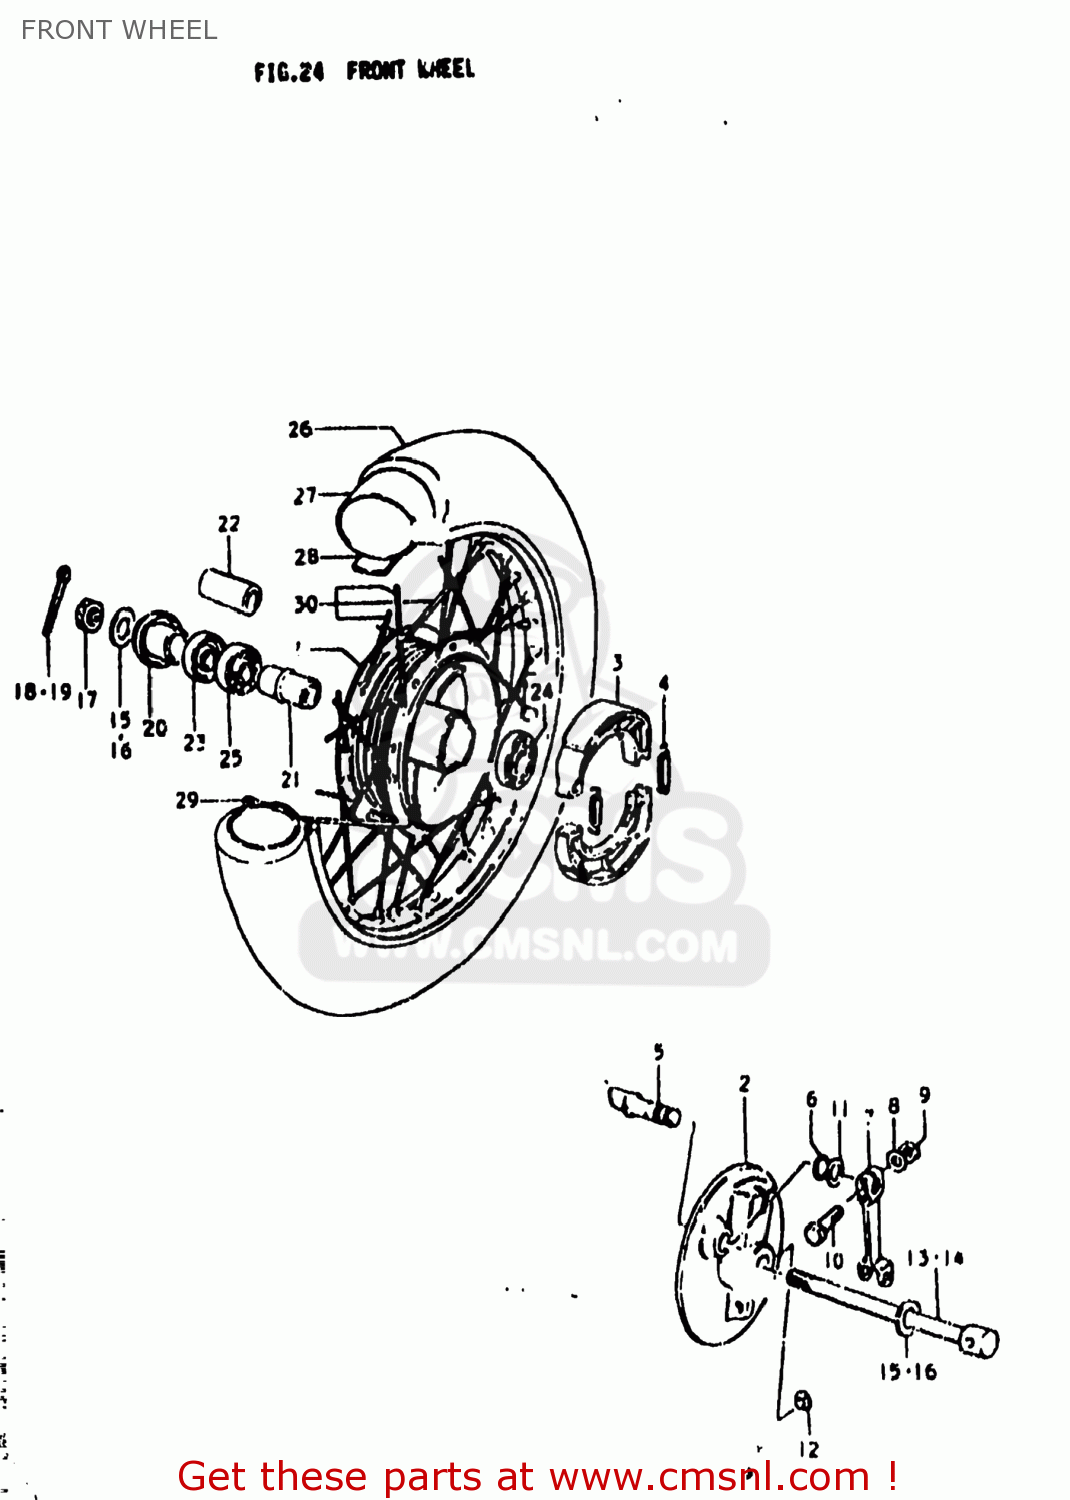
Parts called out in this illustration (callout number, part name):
1	HUB,FRONT
2	PANEL,FRONT HUB
3	SHOE,BRAKE
4	SPRING(L:34)
5	CAM,FRONT BRAKE
6	O-RING (D:2.4 ID:13.8)
7	LEVER,FR BRAKE CAM
8	WASHER
9	NUT
10	BOLT(6X33)
11	WASHER (14.5X22X1.6)
12	CAP(OD:17)
13	AXLE,FRONT
14	AXLE,FRONT
15	WASHER
16	WASHER(10.5X22X2.3)
17	NUT
18	COTTER PIN
19	PIN 20X20
20	SPACER,FRONT AXLE,RIGHT
21	SPACER,FRONT HUB BEARING
22	SPACER (10.2X16X51)
23	SEAL,OIL(15X31X5)
24	BEARING
25	BEARING
26	TIRE,FRONT
27	TUBE,INNER
28	PROTECTOR,INNER TUBE
29	RIM,FRONT WHEEL (1.40X14)
30	SPOKE SET,FRONT
